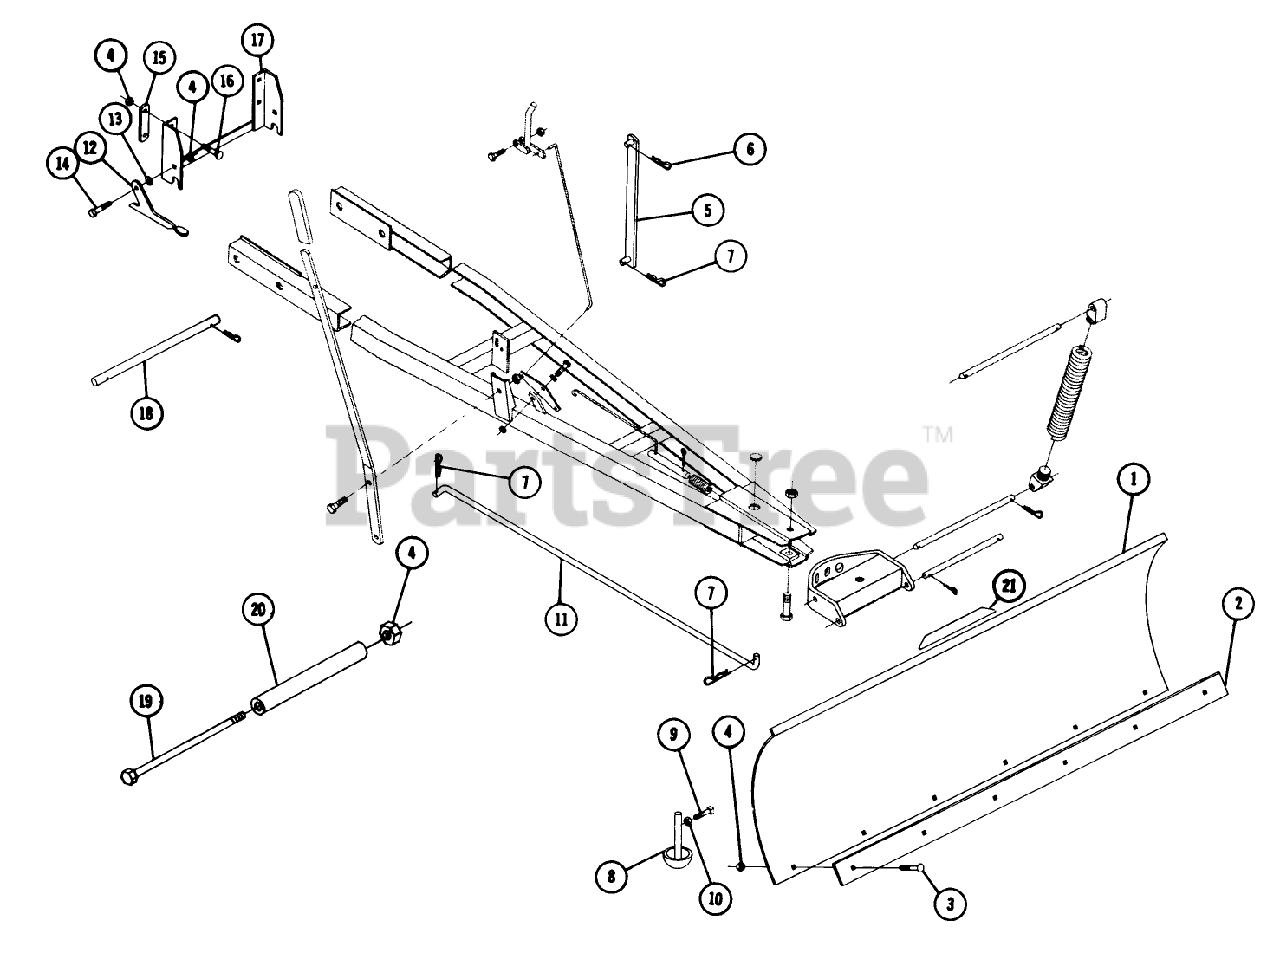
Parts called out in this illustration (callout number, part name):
1	Ass-y-Blade
2	Plate-Blade Edge
3	Bolt-3/8-16 x 3/4
4	3/8-16 E.S.
5	Lift Bar
6	Hairpin
7	Hairpin
8	Skid
9	Set Screw 3/8-16 x 5/8 Sq. HD.
10	3/8-16 Jam Nut
11	Rod-Blade Control
12	Latch Hitch
13	Washer
14	Bolt 3/8-16 x 1
15	BRACKET-REAR LINK MOUNTING
16	Bolt-Carr. 3/8-16 x 3 1/2
17	Breather
18	Shaft-Cross (6-9611 only)
19	Bolt-Hex. 3/8-16 x 8 1/2
20	Spacer (6-9611 only)
21	Decal
